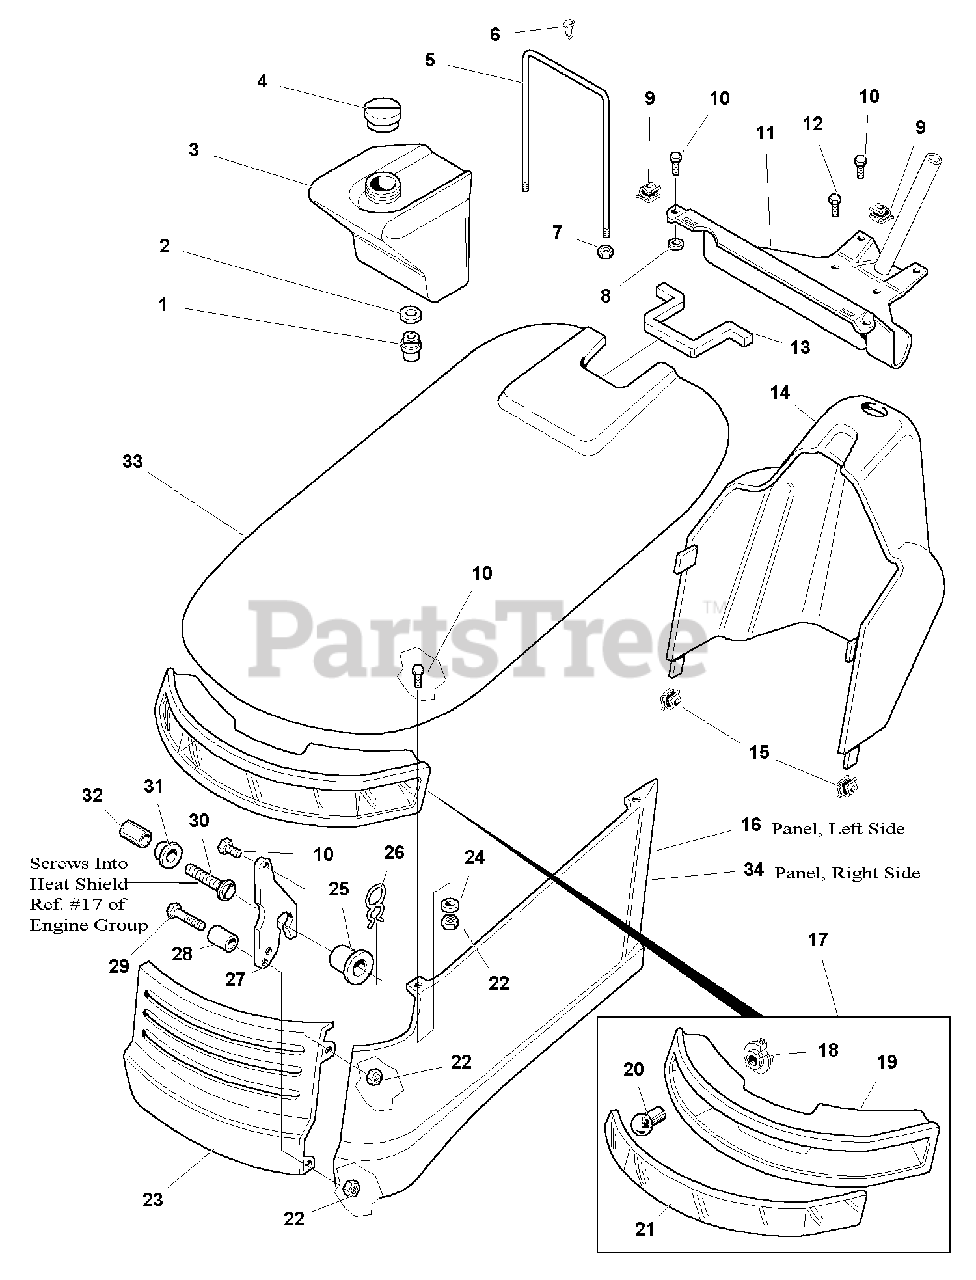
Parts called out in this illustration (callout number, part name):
1	FITTING, Fuel
2	GROMMET, Fuel Fitting
4	CAP, Fuel Tank
6	FASTENER, Plastic, Ratchet
7	NUT, Hex Nylon Lock, 5/16-18
8	WASHER, 1/4
9	PAL NUT, 1/4-20
10	CAPSCREW, Hex Head Whiz Lock, 1/4-20 x 5/8
11	BULKHEAD ASSEMBLY
12	CAPSCREW, Taptite Hex Washer Head, 1/4-20 x 1/2
13	GROMMET, Strip
16	PANEL, Side, LH, Orange
16	PANEL, Side, LH, Red
17	LIGHT BAR ASSEMBLY (Includes Ref. Nos. 18, 19, 20 & 21)
18	SOCKET, Bulb
20	BULB, #1156
22	NUT, Hex, Nylon Lock, 1/4-20
23	GRILLE, Orange
23	GRILLE, Red
24	WASHER, Plain, 1/4
25	SPACER, Plastic, Hood Pivot
26	CLIP, Pivot Spacer Retaining
27	HINGE, Hood
29	CAPSCREW, Hex Head, 1/4-20 x 1-1/2
30	CAPSCREW, Hex Head Whiz Lock, 5/16-18 x 1-1/4
31	SPACER, Steel, Hood Pivot, Grooved
32	SPACER, Steel, Hood Pivot
33	HOOD, Orange (15 & 16 HP Only)
33	HOOD, Orange (17 HP Only)
33	HOOD, Red (15 & 16 HP Only)
33	HOOD, Red (17 HP Only)
34	PANEL, Side, RH, Orange
34	PANEL, Side, RH, Red
